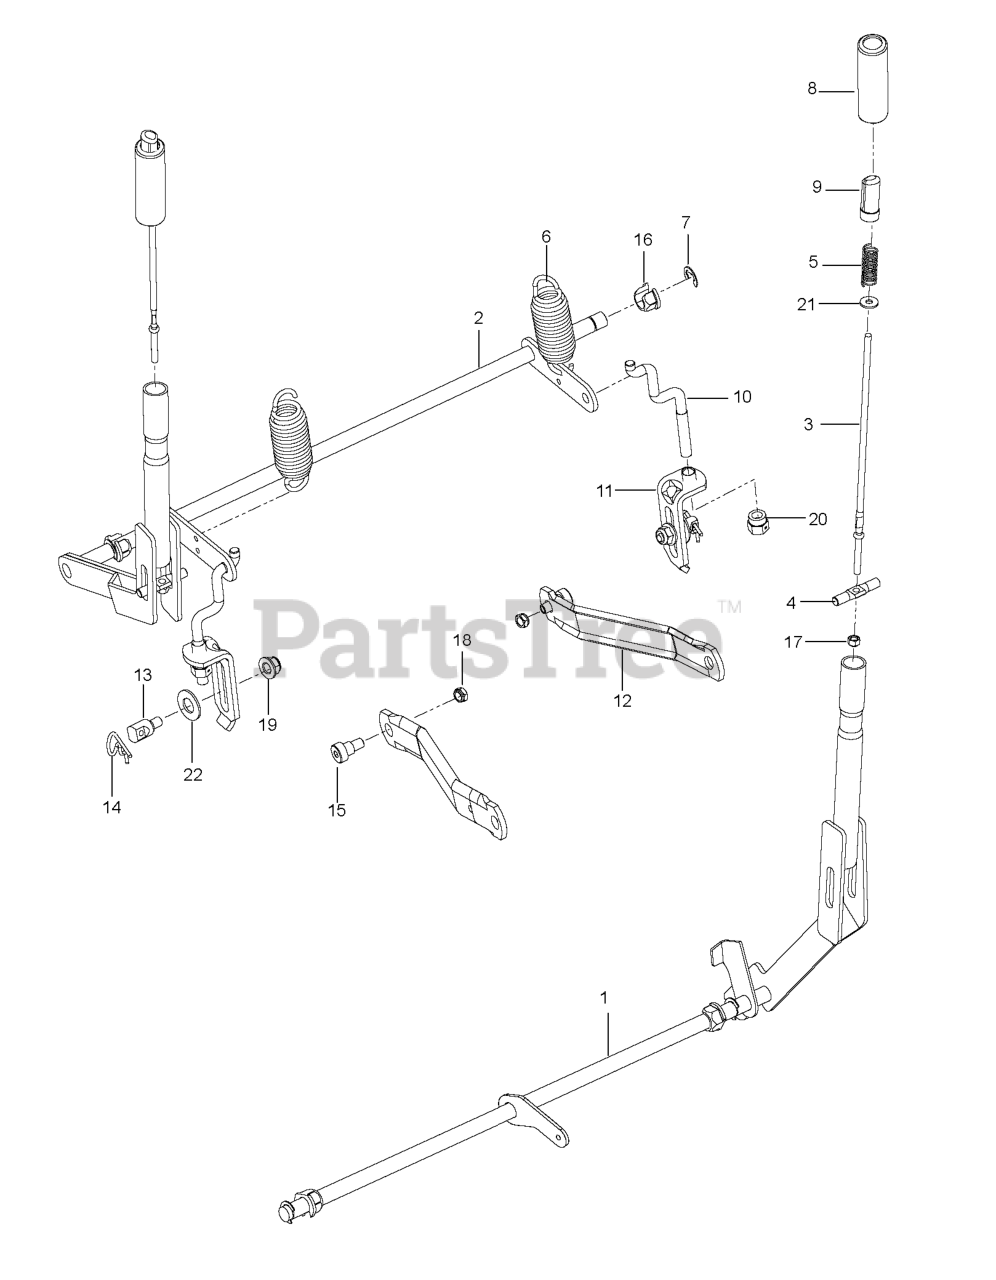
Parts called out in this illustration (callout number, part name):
1	SUBASM.SHAFT.BRAKE.WLDMNT.MED
2	DECK.LIFT.PNT.WELDMENT.RZ.BLK
3	ROD, HANDLE RELEASE
4	ROD LATCH RELEASE
5	SPRING, COMPRESSION
7	RETAINING RING LT
8	GRIP, HANDLE, BLACK 4"
9	BUTTON, PUSH, BLACK
10	LINK, REAR SUSPENSION
11	ASSEMBLY, BRKT LINK
12	ARM.SUSPENSION.MOWER
13	STUD.FASTNER.W/ANTI-ROTATE
14	HAIRPIN #4
15	SB 3/8-16 X 3/8 SKT HD ZD
16	PLASTIC NUT
17	LOCKNUT.NYLOC.1/4-20
18	NUT HEX 3/8-16 NYLON, THIN
19	5/16-18 NYLOC FLANGE NUT
20	NUT, LIFT LINK 7/16-20
22	WASHER
